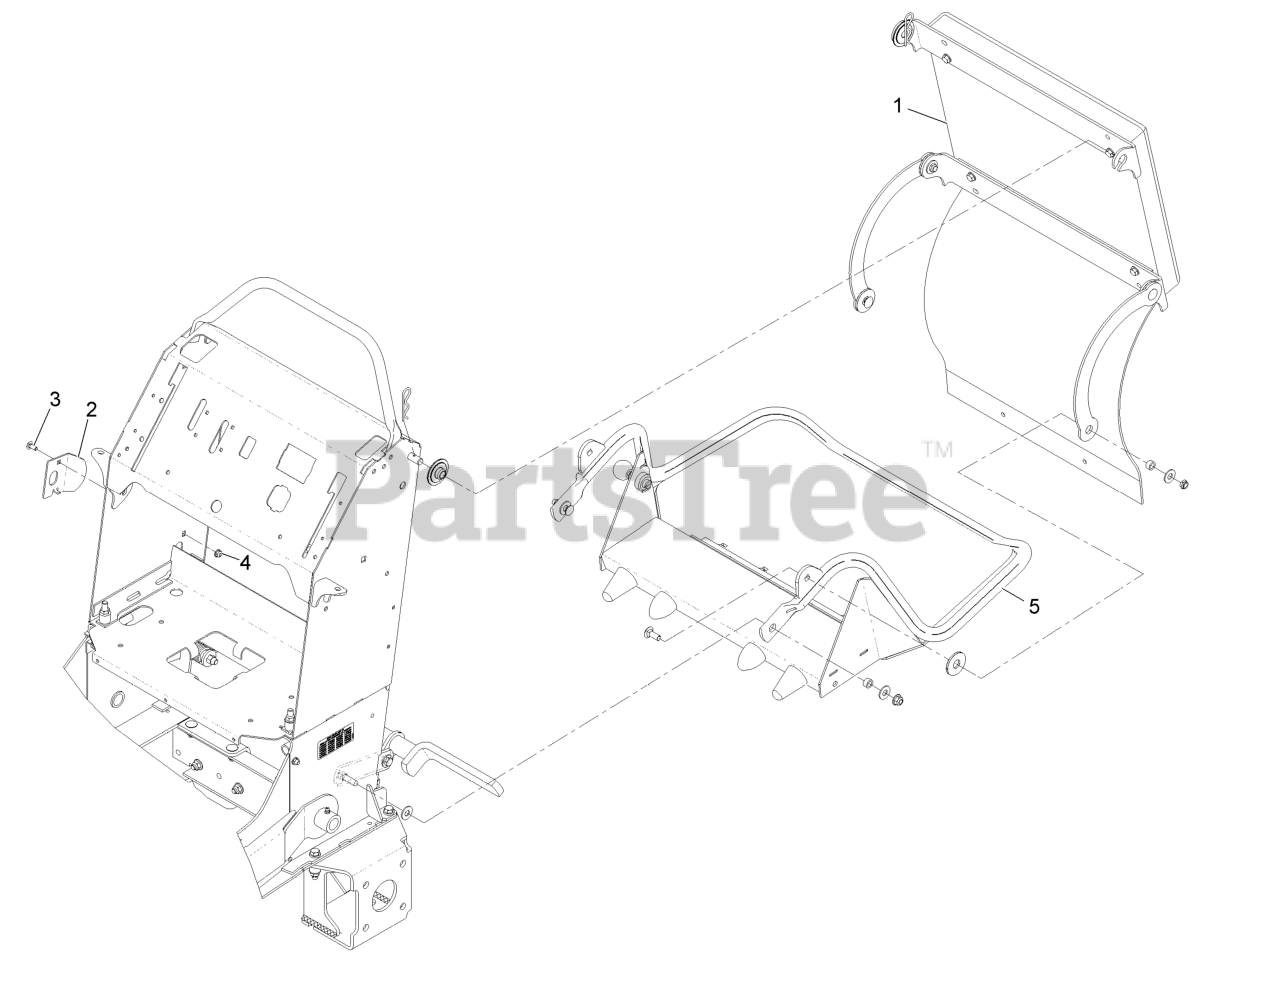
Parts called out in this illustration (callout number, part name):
2	PLATE-STRIKER
3	SCREW-CARR
5	ASM,PLATFORM
